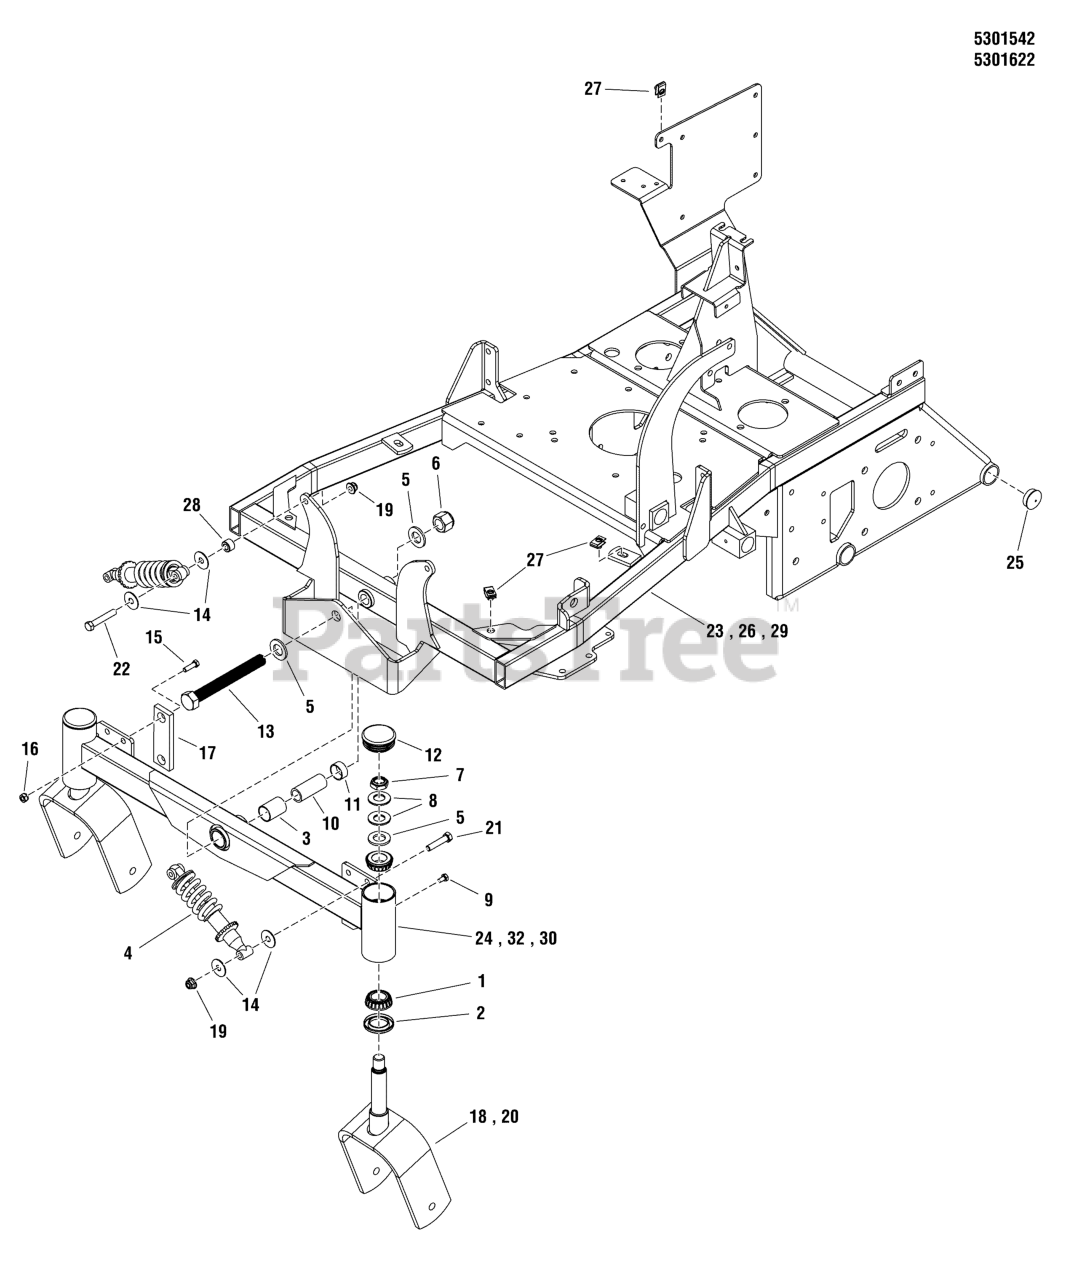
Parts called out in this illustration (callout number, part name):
1	BEARING, TAPERED ROLLER, 1
2	SEAL, GREASE
3	PIVOT BEARING-1.00 X 1.125 ODX1.50
4	SHOCK, SPRING ASSEMBLY
5	WASHER, 3/4 SAE
6	NUT, 3/4-16 HEX NYLON LOCK
7	NUT, 3/4-16, HEX JAM NYLON LOCK
8	WASHER, BELLEVILLE - 1.500 X .755
9	BOLT, 1/4-28 X 1/2, GD5 YZ
10	SPACER, .75 X 1.00 X 2.38
11	PIVOT BEARING, 1.00 X 1.125 OD X .50
12	CAP, GREASE, LOW PROFILE
13	BOLT, 3/4-16 X 6-1/2 YZ GD5
14	WASHER-3/8 FENDER
15	SCREW, 5/16-18 X 1 PHILLIPS HD, BZ
16	NUT, 5/16-18 HEX NYLON LOCK
17	PAD, FRICTION, .375 X 1.25 X 4.00
18	WELD, CASTER YOKE - RED
19	NUT, 3/8-16 HEX NYLOCK FLANGE
20	WELD, CASTER YOKE - RED
21	BOLT, 3/8-16 X 1-3/4" GD5 CZ
22	BOLT, 3/8-16 X 2-1/4" GD5 CZ
23	WELD, MAIN FRAM
24	ASSM, FRONT END PIVOT
25	PLUG, PANEL, 1.25 - BLACK
26	WELD, FRONT FRAME
27	BODY CLIP, 5/16-18-7GA MATERIAL
28	SPACER, .39 X .75 X .50, CZ
29	WELD, MAIN FRAME, EVOLUTION, 48 - RED
30	ASSM, FRONT END PIVOT
32	ASSM, FRONT END PIVOT
